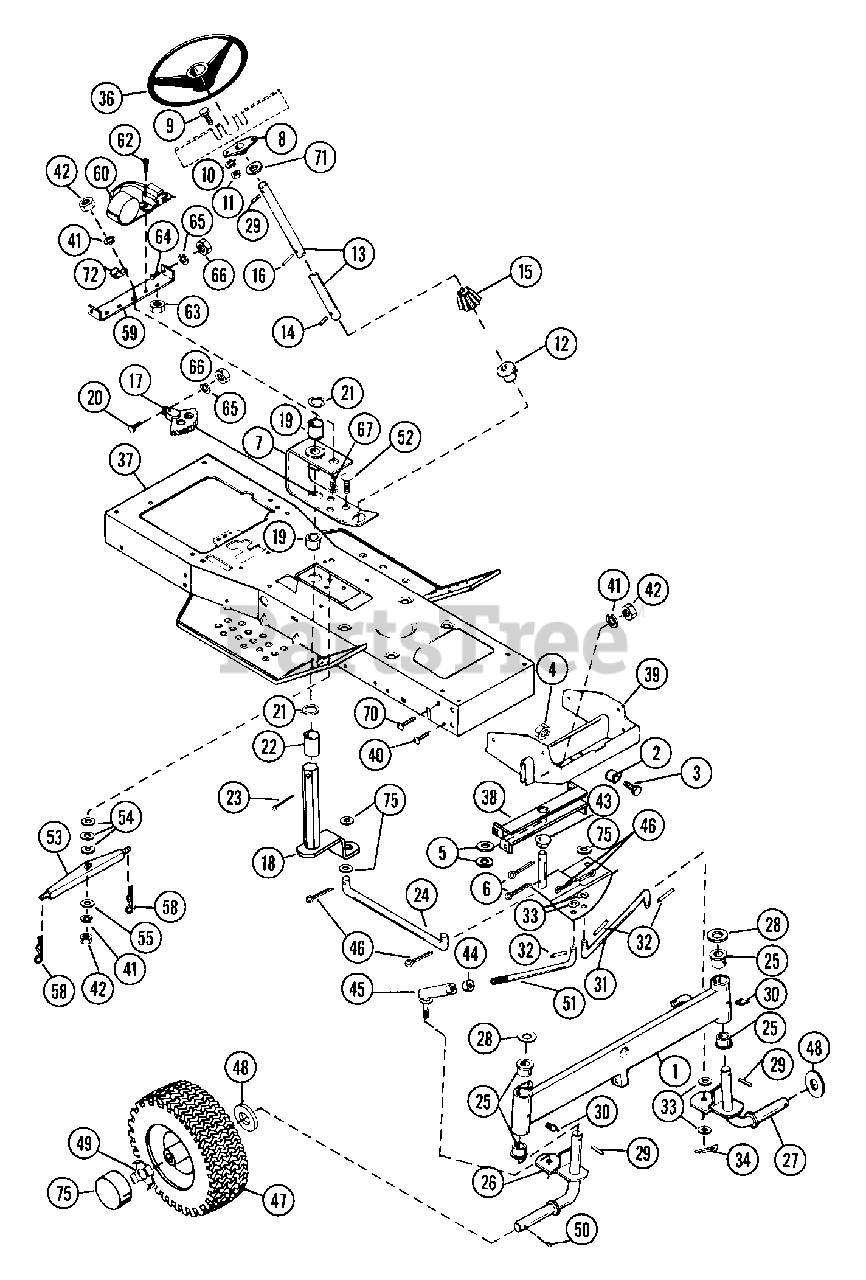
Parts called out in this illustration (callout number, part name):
1	AXLE W/BUSHINGS
2	SPACER .531X.748X.524
3	BLT-HEX .50-13X1.25 PL GR5
4	NUT-LK-CROWN .50-13 GR C PL
5	WSHR-FL-STL.656X1.312X.095 PL
6	PIN-COTR .12 X 1.25 PL
7	STEERING BRACKET
8	BRG-FLG .751X2 HOLESX.81
9	BLT-HEX .31-18X.75 PL GR5
10	WSHR-LK .312X.097 PL HVY
11	NUT-HEX .312-18
12	BSHG-FLG .750X1.093X.625X1.375
13	STEERING COLUMN
14	PIN .249X1.125 DRIV-LOK SP
15	PINION GEAR-STEERING
16	PIN-ROLL .188X1.13
17	STEERING BEVEL GEAR
18	ARM & SHAFT
19	BSHG-SLV .750X1.000X.750 HX SB
20	BLT-HEX .31-18X1.75 PL GR2
21	WSHR-FL-STL .875X1.250X.075
22	SPACER .780X.900X2.094
23	PIN-COTR .18X1.25 PL
24	STEERING LINK
25	BSHG-FLG .750X1.000X.750X1.250
26	RIGHT SPINDLE WELDMENT
27	LEFT SPINDLE WELDMENT
28	WSHR-FL-STL .755X1.375X.093
29	PIN-ROLL .250X1.25
30	SPIN DRIVE ZERK FITTING
31	DRAG LINK
32	PIN-ROLL .125X1.00
33	WSHR-FL-STL .520X.827X.062 YZ
34	PIN-COTR .12X1.0 PL
35	STEERING PIVOT
36	STEERING WHEEL
37	MAIN FRAME
38	STEERING PIVOT CHANNEL
39	FRONT AXLE SUPPORT
40	BLT-RDHDSQNK .38-16X.75 SHT PL
41	WSHR-LK .375X.115 HVY PL
42	NUT-HEX .375-16
43	FLANGE BUSHING
44	NUT-JAM .50-20 PL
45	BALL JOINT R.H.
46	PIN-COTR .12X1.0 PL
47	WHEEL & TIRE ASSEMBLY
47	BRG-BALL .752X1.50X.50
48	WSHR-FL-STL .755X1.375X.093
49	SPINDLE CUP
50	PIN-COTR .25X1.50 ST PL
51	DRAG LINK
52	BLT-RDHDSQNK .38-16X1.25 PL
53	PIVOT ARM
54	WSHR-FL-STL .380X.626X.033
55	WSHR-FL-STL.406X.812X.065PL
58	PIN-HAIR INT .08X.18X1.18
60	MODULE
61	CONNECTOR
63	NUT-KEPS 10-24 PL
64	BLT-HEX .31-18X.75 PL GR5
65	WSHR-LK .312X.097 PL HVY
66	NUT-HEX .312-18
67	BLT-HEX .38-16X1.00 PL
70	BLT-RDHDSQSHNK .38-16X1.00 PL
71	WSHR-FL-STL .754X1.125X.062 PL
75	WSHR-FL-STL .505X.880X.072 PL
